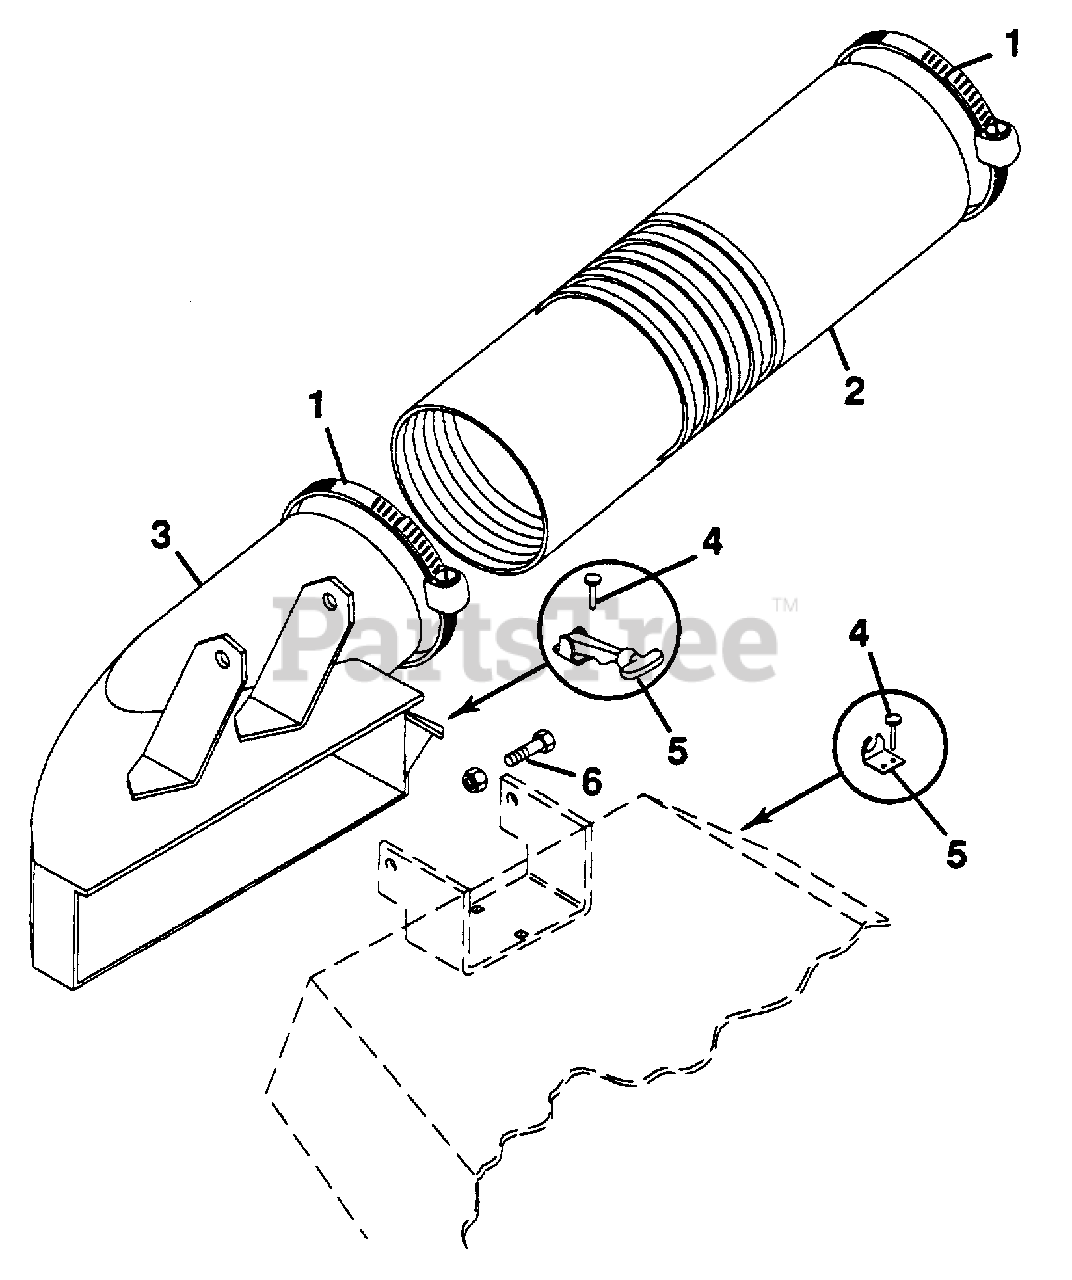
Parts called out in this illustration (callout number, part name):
1	Clamp
2	Hose, Mower to Blower
3	Weldment, 60" Boot
4	Rivet, Dome Head
5	Latch, Flexible Draw
6	Bolt, Hex 3/8-16x1.50
